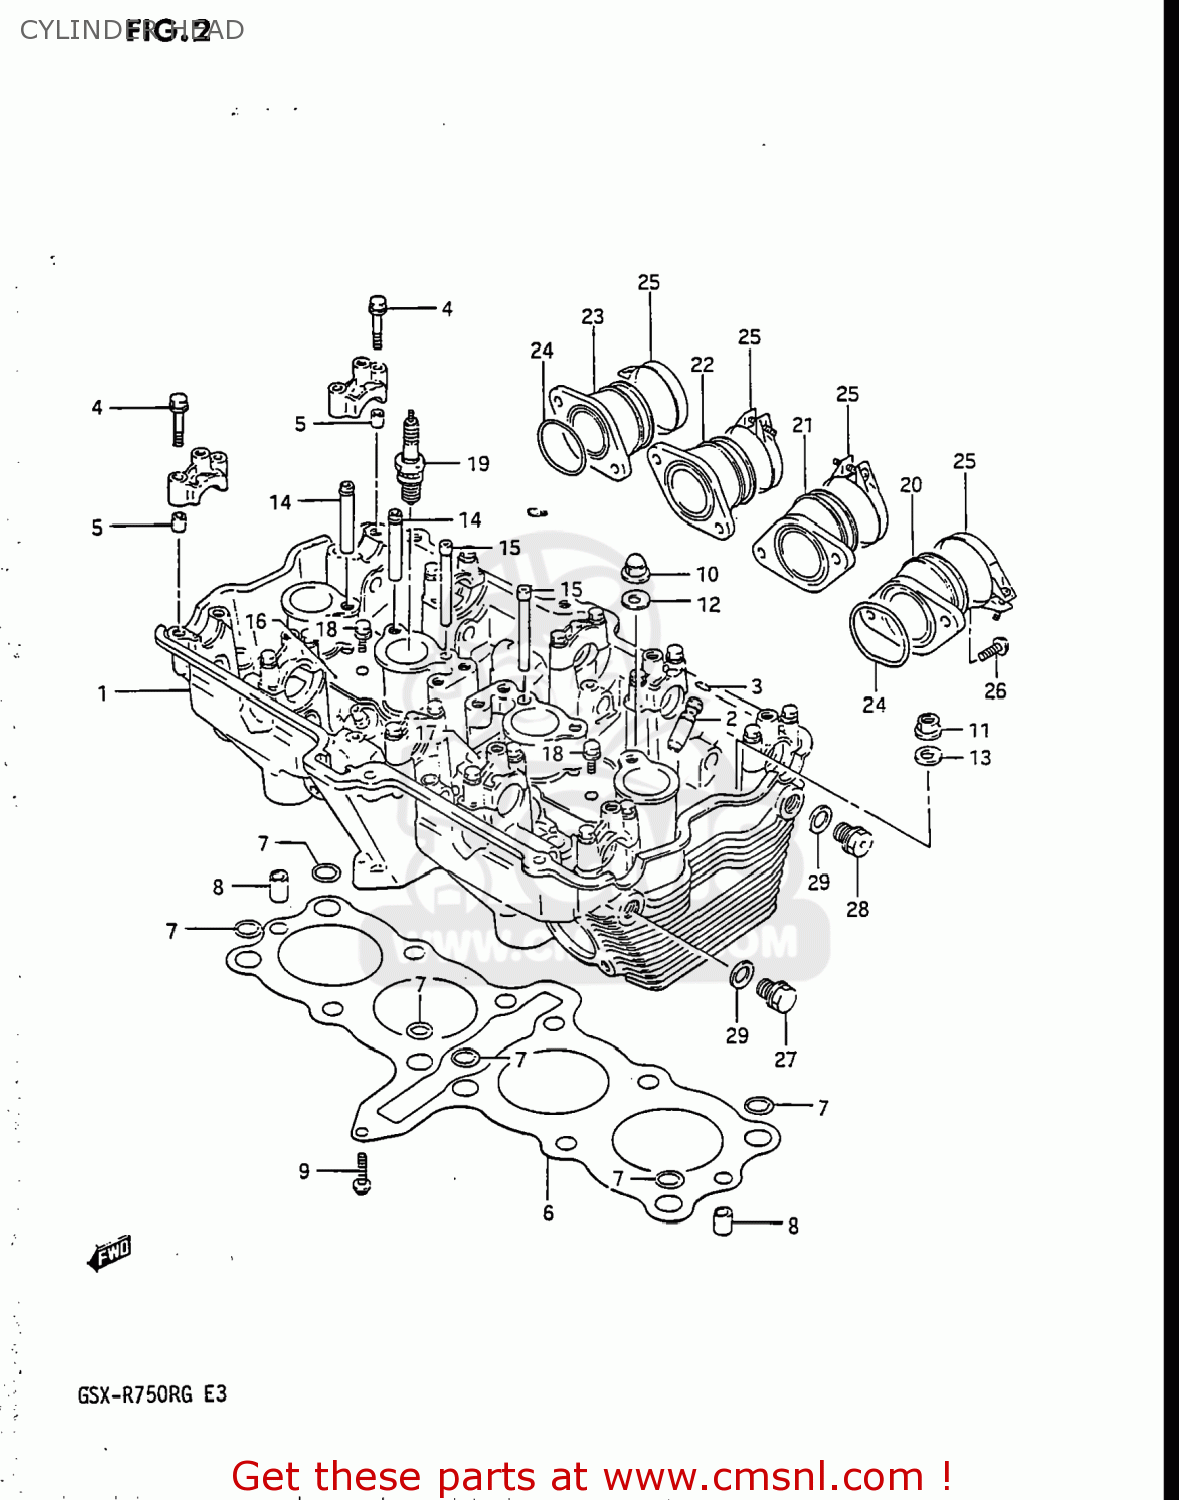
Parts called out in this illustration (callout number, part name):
1	HEAD ASSEMBLY,CYLINDER
2	GUIDE,VALVE
3	RING,SNAP
4	BOLT(6X39)
5	PIN(6.2X8X11)
6	GASKET,CYLINDER HEAD (NAS)
7	O RING(D:2.4,ID:12.3)
8	PIN
9	BOLT
10	NUT
11	NUT
12	GASKET(10.2X20X2).3 (NAS)
13	WASHER (10.5X22X2.3)
14	PIPE,OIL NO.1
15	PIPE,OIL NO.3
16	PLATE,OIL PIPE,R
17	PLATE,OIL PIPE,L
18	BOLT
19	SPARK PLUG D9EA
20	PIPE,INTAKE
21	PIPE,INTAKE
22	NET,INTAKE
23	PIPE,INTAKE
24	O RING(D:2.4,ID:39.7)
25	CLAMP
26	SCREW
27	PLUG
28	PLUG
29	GASKET(14X19.2X2) (NAS)
